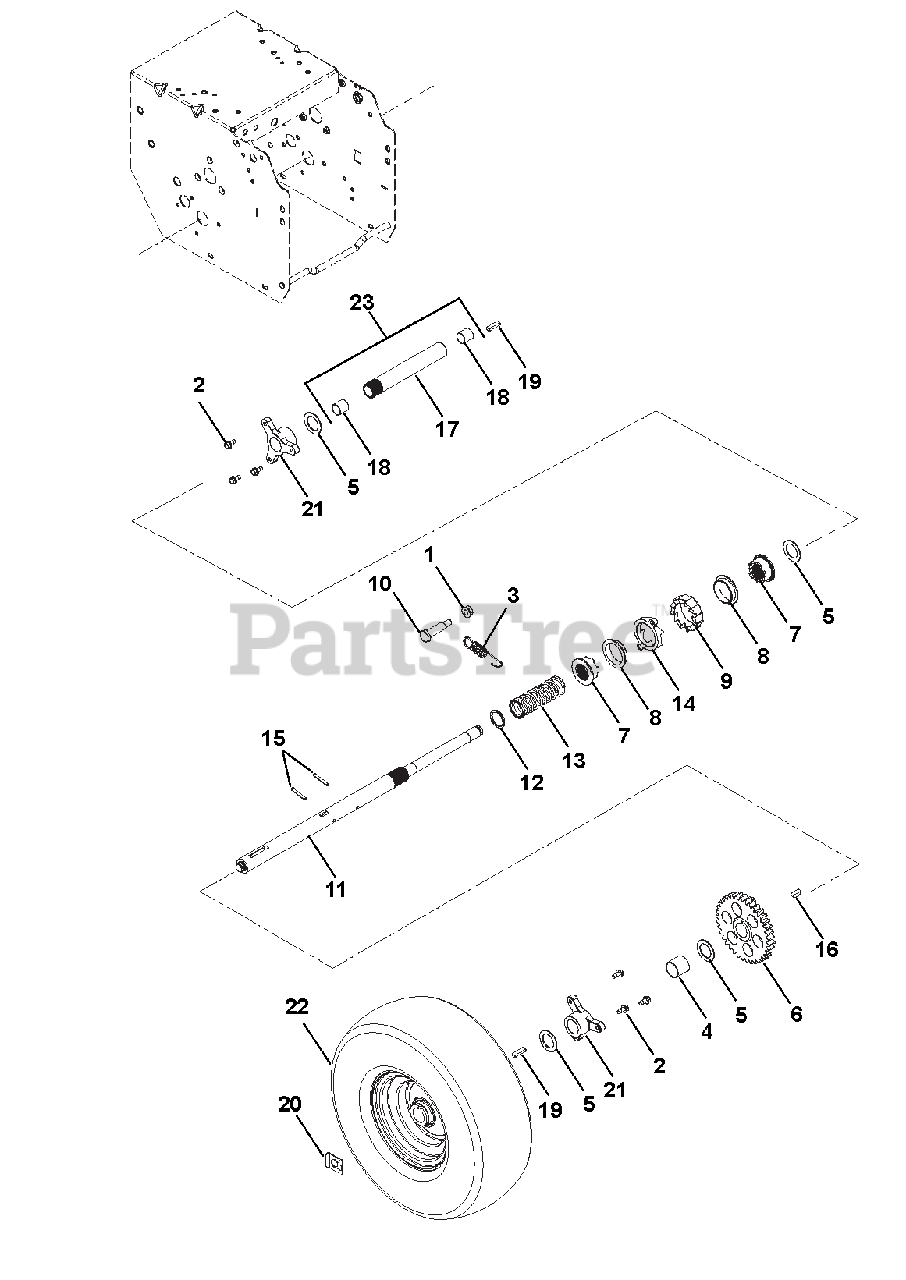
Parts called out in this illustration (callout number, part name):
1	@NUT-LK-TOP-FLG .38-16 YWZC
2	SCR-TAP .25-20X.50 HWH TR YWZ
3	SG-TENS .06X.62X2.94
4	BSHG-SLV, 1.012X1.125X1.00
5	WSHR-FL-STL 1.010X1.505X.062YZ
6	GEAR, SPUR
7	CLUTCH, DOG - SLIDING
8	BUSHING, FLANGE
9	GEAR, RATCHET
10	BLT-SHLDR .50X1.52 .38-16X.635
11	AXLE, LONG - CLICKER
12	WSHR-FL-STL 1.010X1.250X.068YZ
13	SPRING, COMPRESSION
14	GEAR, CLUTCH
15	PIN-ROLL .188X1.25
16	KEY-WDRF .25X.750X.313 SAE91
17	AXLE, SHORT - CLICKER
18	BSHG-SLV .706X.764X.75 BRZ
19	KEY-RECT .25X.188X1.00
20	CLIP, SNAP .625 DIA
21	BUSHING, AXLE
22	TIRE/WHEEL,15X5-6 REMOTE K398A
23	AXLE, CLICKER W/BUSHINGS
